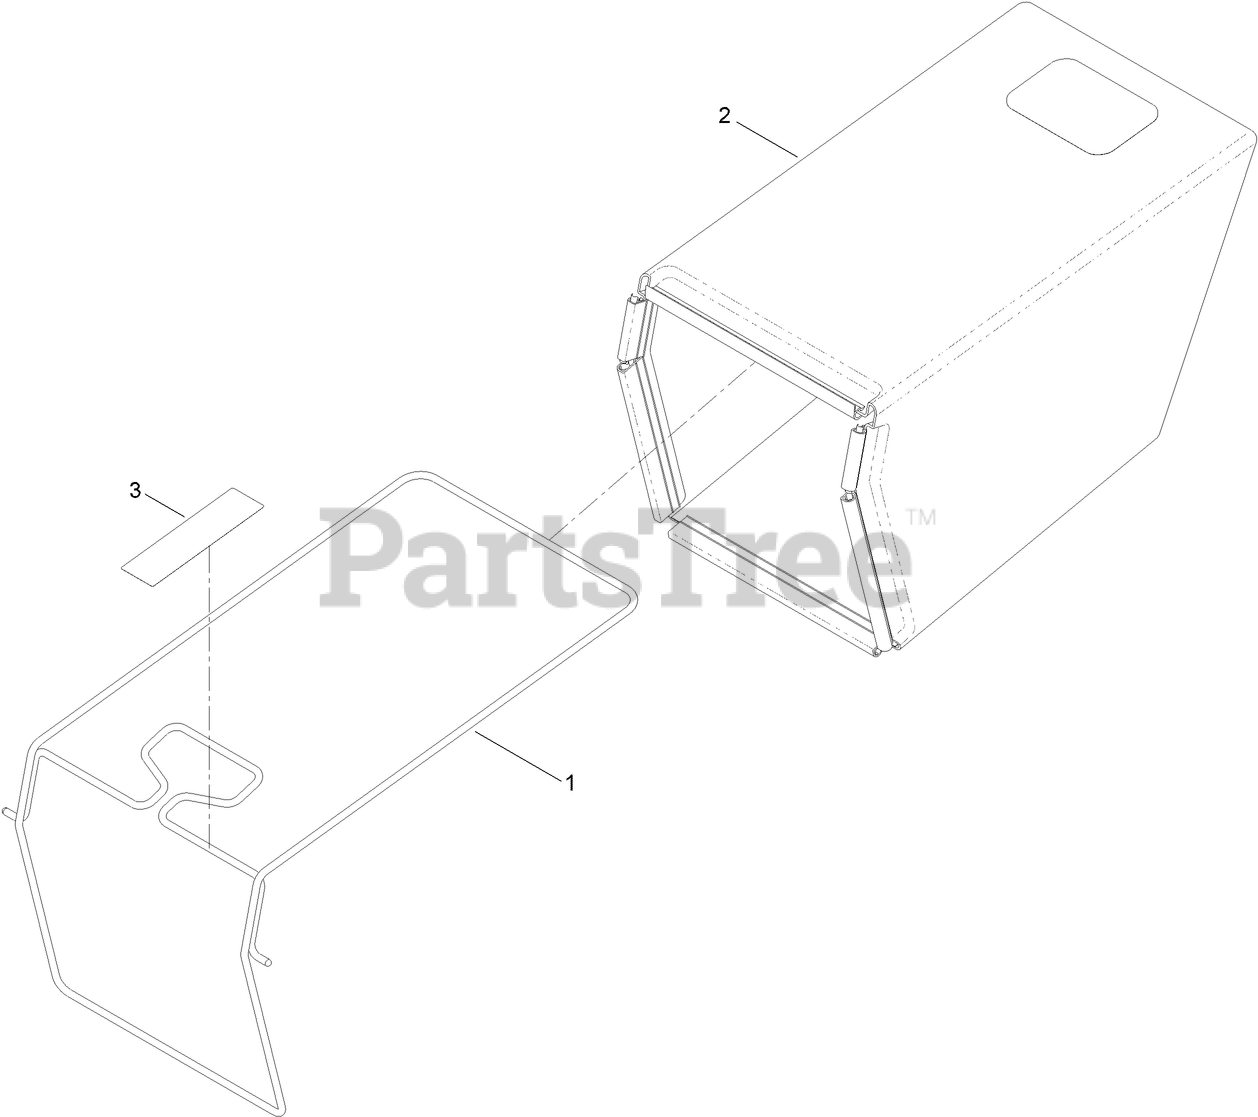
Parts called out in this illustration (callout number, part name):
1	ASM-FRAME, BAG
2	ASM-BAG, GRASS
3	Decal-Warning
